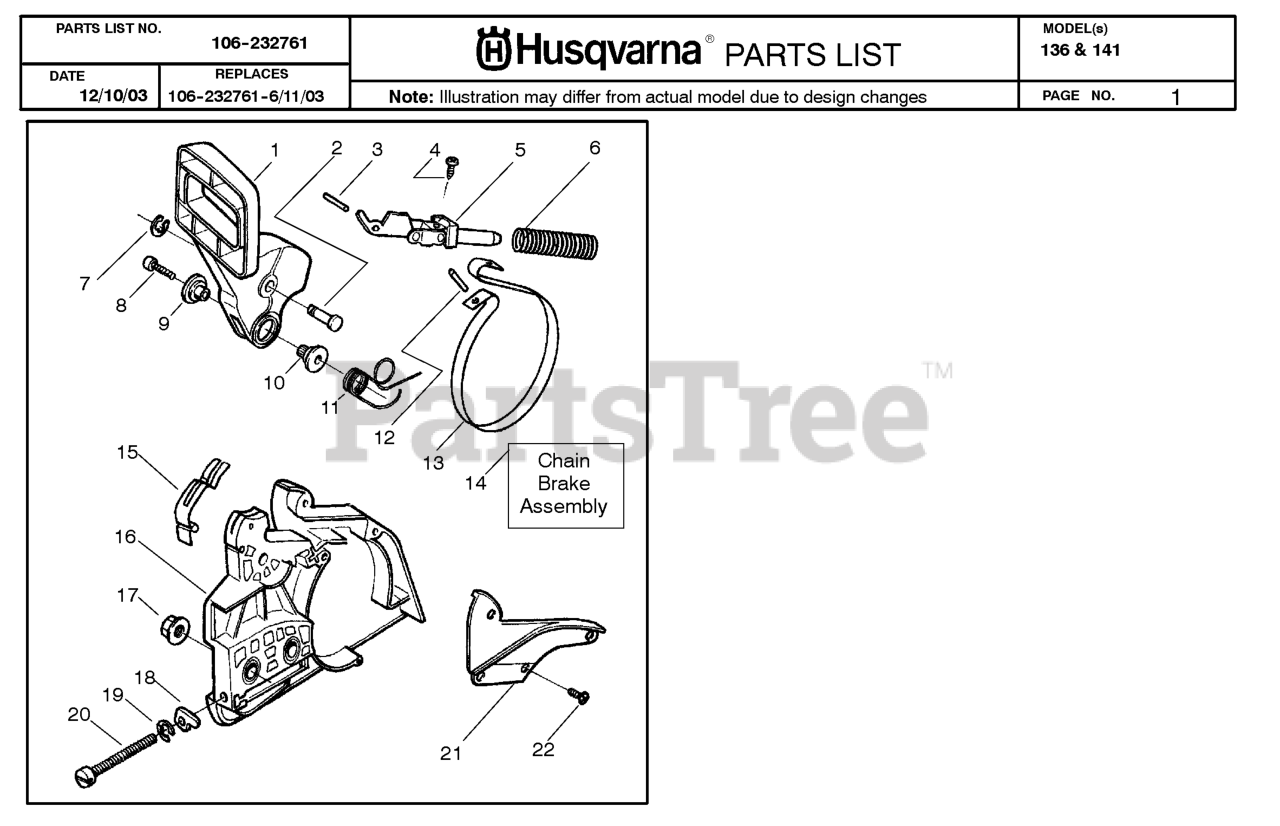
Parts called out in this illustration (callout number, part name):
4	SCREW
5	FRONT LINK ASSY
6	%COMPRESSION SPRING
9	JOURNAL, RIGHT
10	SHAFT PIVOT
11	SPRING,BRK HDL 36/41
13	BRAKE BAND
14	CHAIN BRAKE ASM.
15	SPRING-POSITION
16	CLUTCH COVER
18	ADJUST PIN,BAR 36/41
20	BAR ADJUSTING SCREW
21	CHAIN BRAKE COVER
22	SCREW
